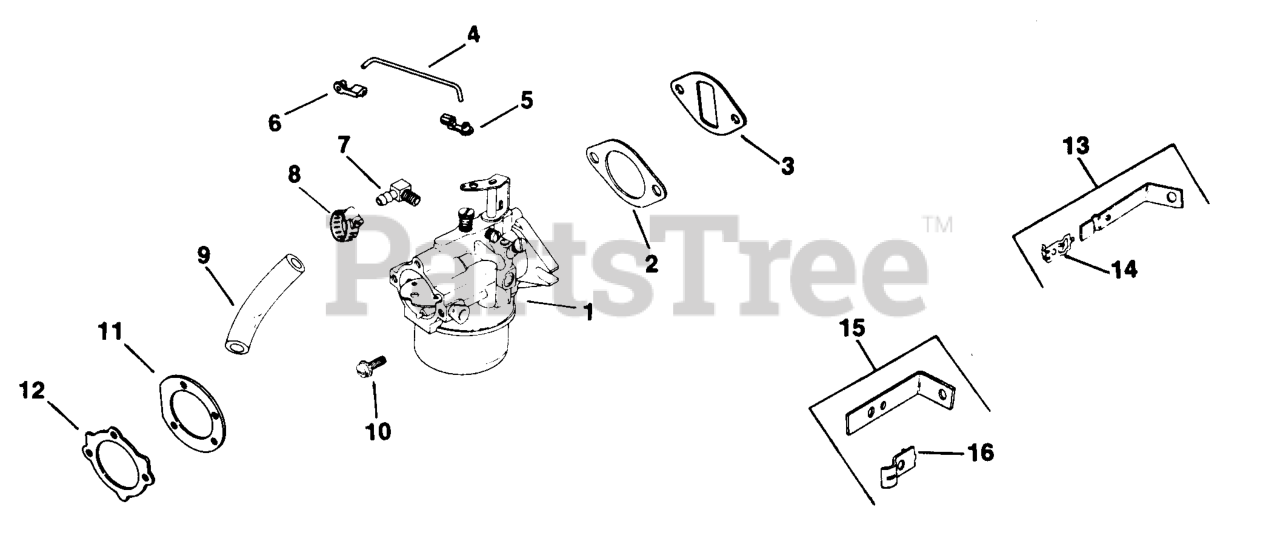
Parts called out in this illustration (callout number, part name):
3	GASKET, CARBURETOR
7	CONNECTOR, 90 DEG. HOSE
10	SCREW, SLT HD 5/16-18X1" - DISCONTINUED
15	BRACKET - DISCONTINUED
2575702-S	KIT, CARBURETOR REPAIR
